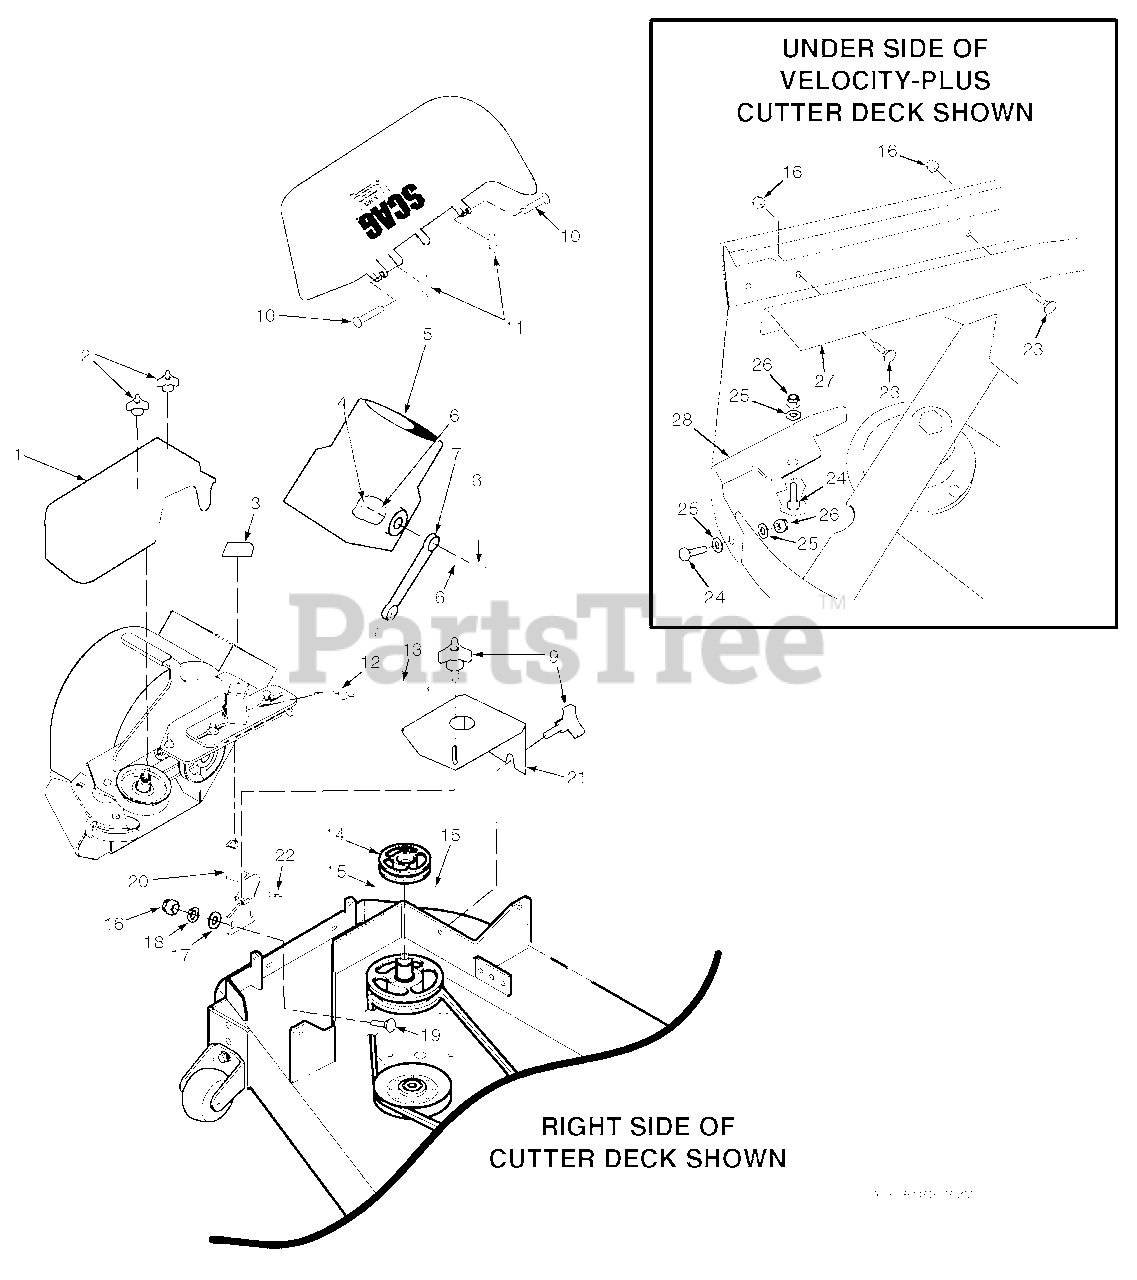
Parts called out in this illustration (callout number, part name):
1	Belt Cover, GC-STT - 61"
2	Wingnut, Plastic 3/8" Small
3	Cap, Square Vinyl
4	Nut, Elastic Stop 1/4-20
5	Adapter, Blower GC-STT
6	Flatwasher, 1/4-.312 x .750 x .065
7	Rubber Strap 7-3/4"
8	Bolt, Hex Head 1/4-20 x 1-1/4"
9	Knob W/Stud, 3/8-16 x 1-1/4"
10	Clevis Pin, 5/16 x 1-1/2"
11	Pin, Rue Cotter 5/16 Dia.
12	Pin, Ring 1/2 x 2-1/4"
13	Lanyard
14	Pulley, 5-1/2" for 61" Deck
15	Setscrew, 5/16-18 x 3/8"
16	Nut, Elastic Stop 3/8-16
17	Lockwasher, 3/8"
18	Flatwasher, 3/8-.391 x .938 x .105
19	Bolt, Carr. 3/8-16 x 1-1/4" Grade 5
20	Mounting Post Weldment, Blower - 61"
21	Belt Cover Assembly, GC-STT-61V w/Cap
23	Bolt, Carriage 3/8-16 x 1"
24	Bolt, Hex Head 5/16-18 x 1"
25	Flatwasher, 5/16-.375 x .875 x .083
26	Nut, Elastic Stop 5/16-18
27	Baffle, Front 61" Deck
28	Baffle, Turbo 61" Deck
